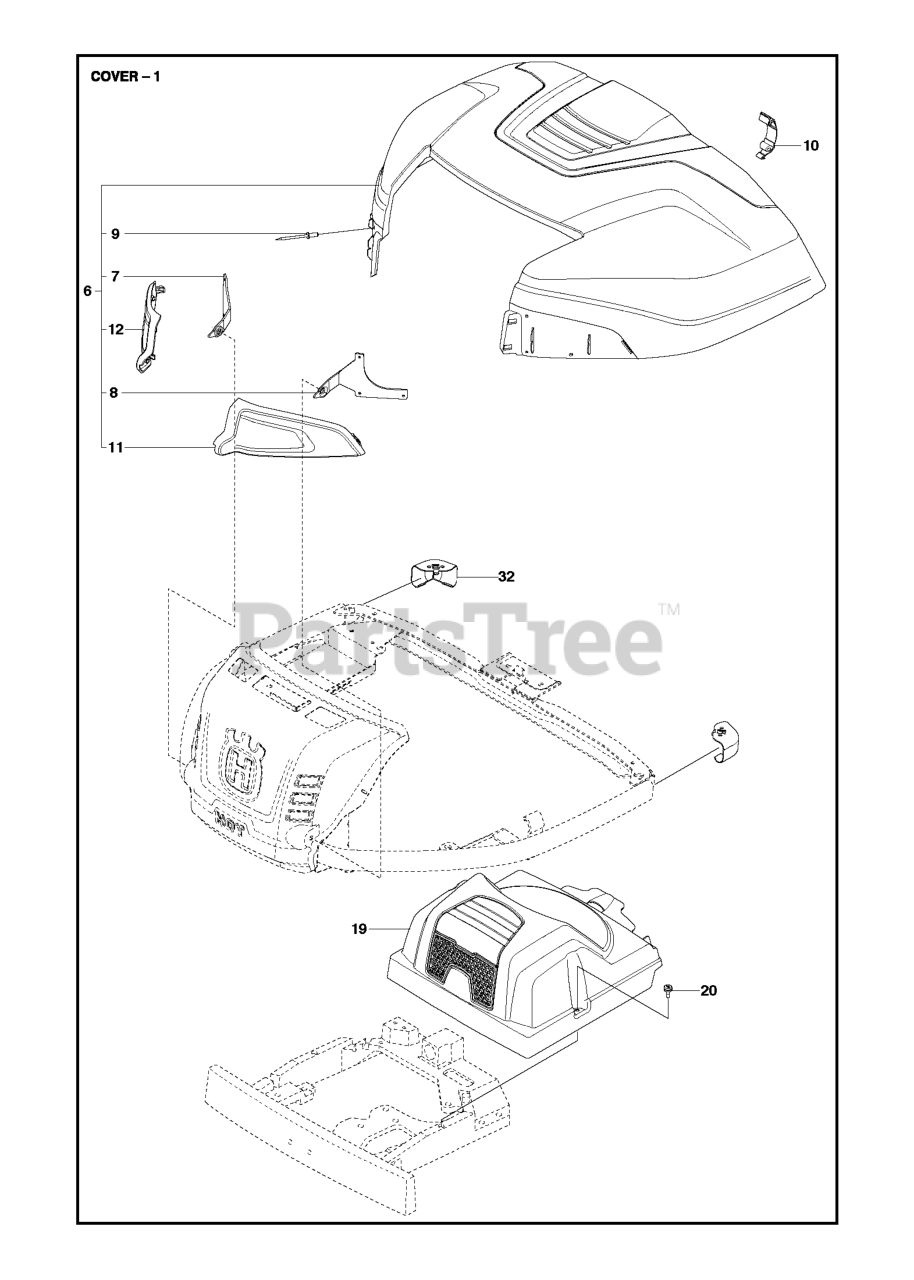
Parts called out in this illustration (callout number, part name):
6	ENGINE HOOD ASSY
10	CLIP GRAY
19	TRANSMISSION COVER
